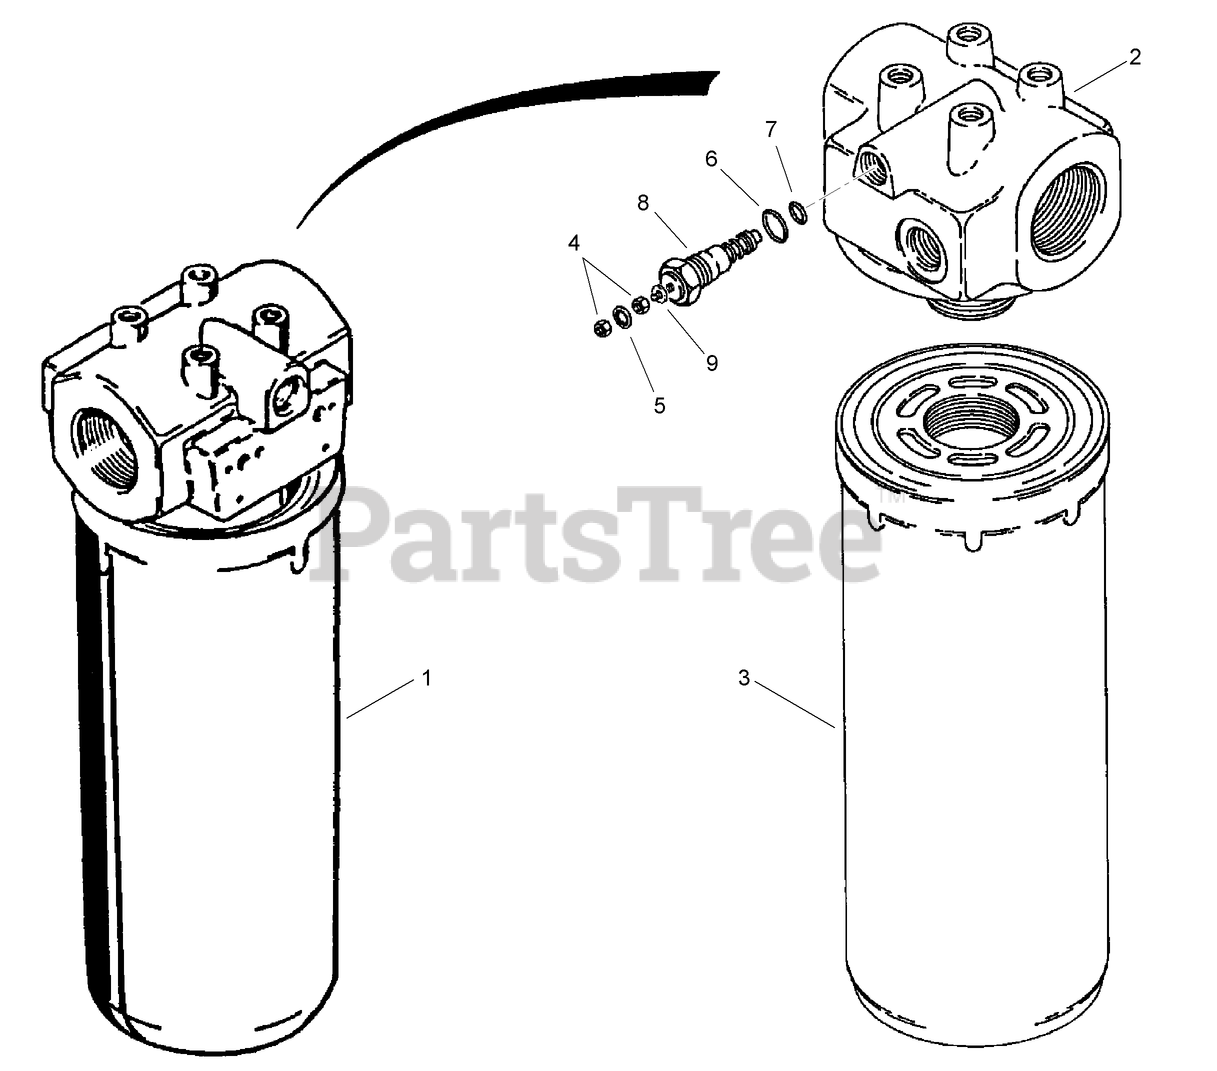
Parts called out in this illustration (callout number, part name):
1	OIL FILTER ASM
2	HEAD - Filter (bypass valve components are not serviced separately)
3	ELEMENT ASM-Filter
4	NUT-Hex, Left-hand Thread, No. 10 NF
5	WASHER-Internal Tooth Lock, 3/16 inch
7	O-RING-5/16 ID x 1/16 inch Wide, Small
8	INDICATOR - Restriction, Electric
9	WASHER - Identification, Red/White Color
